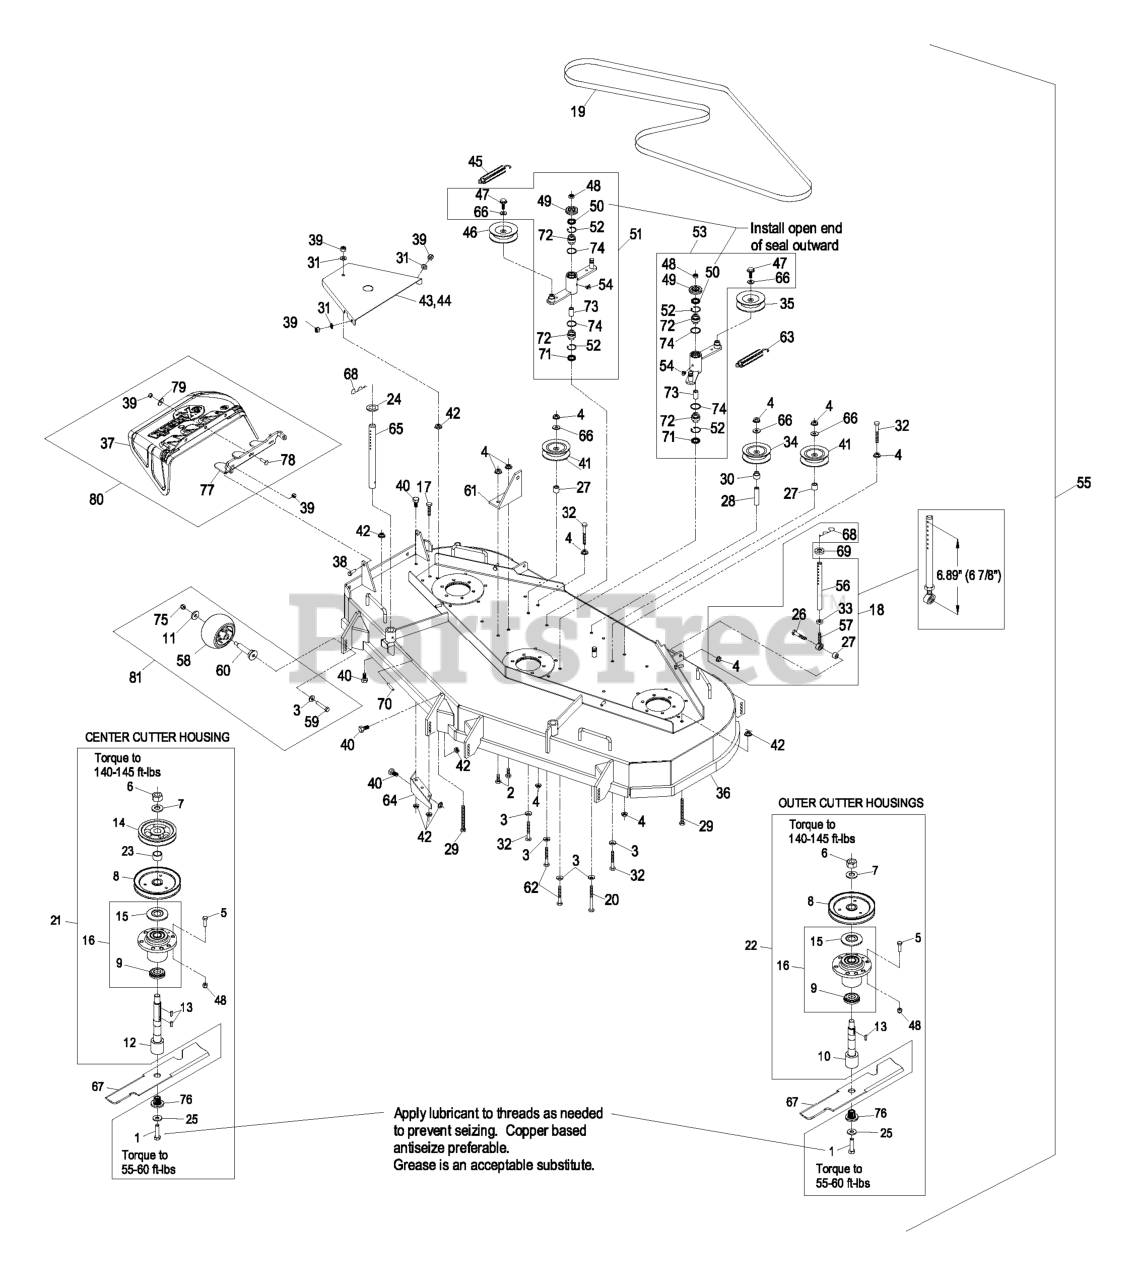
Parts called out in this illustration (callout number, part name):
1	SCREW-HH
2	SCREW-HH
3	WASHER-BELLEVILLE
4	NUT-HHF, WHIZ
5	SCREW-HH
6	NUT-HH
8	SHEAVE,BLADE DRIVE 6.30
9	SPACER-GUARD, BOTTOM
10	KIT, SPLINED SPINDLE 103-
12	KIT, SPLINED SPINDLE 103-
14	SHEAVE,BLADE DRIVE
15	GUARD-BEARING, TOP
16	KIT, CUTTER HOUSING
17	SCREW-HH
18	KIT,SUPPORT LINK W/PIN
19	BELT,MULE DRIVE
20	SCREW-HH
21	ASM, CUTTER HSG FMD604CTR
22	ASM, CUTTER HSG COMPLETE
23	SPACER,TUBE
24	SPACER-DECK SUPPORT
25	WASHER-SPRING
26	SCREW-HH
28	SPACER-ANCHOR, CLUTCH
29	BOLT,TAP HH
30	BUSHING,IDLER
31	WASHER-FLAT
32	BOLT-CARR
33	NUT-HEX
34	PULLEY-IDLER
35	PULLEY-IDLER
37	CHUTE,DISCHARGE
38	SCREW-HH
39	NUT-LOCK, NI
40	SCREW-HH
41	IDLER,PULLEY
43	SHIELD,BELT RH
44	SHIELD,BELT LH
45	SPRING-EXTENSION
46	IDLER,PULLEY
47	SCREW-HHF
48	NUT-LOCK, NI
49	GUARD-TOP
50	SEAL-LIP, SINGLE
51	KIT, IDLER ARM W/BEARINGS
52	RING-SNAP
53	KIT, IDLER ARM W/BEARINGS
54	FITTING-GREASE, 90 DEG
55	Complete Deck Assy
56	LINK,SUPPORT
57	BALLJOINT
58	ROLLER-SCALP, ANTI
59	SCREW-HH
61	BRACKET,SPRING ANCHOR
62	SCREW-HH
63	SPRING-EXTENSION
64	WLD,BAFFLE DISCHARGE
65	ROD,DECK SUPPORT
66	WASHER-FLAT
68	PIN,HAIR COTTER
71	SEAL-LIP, DOUBLE
72	BEARING-SPHERICAL
73	BUSHING-LEVER, LIFT
75	NUT-LOCK, NI
76	BUSHING,SPLINED
77	BRACKET, DISCHARGE CHUTE
78	SCREW-CARR
79	WASHER-FLAT
80	ASM,FMD DISCHARGE CHUTE
